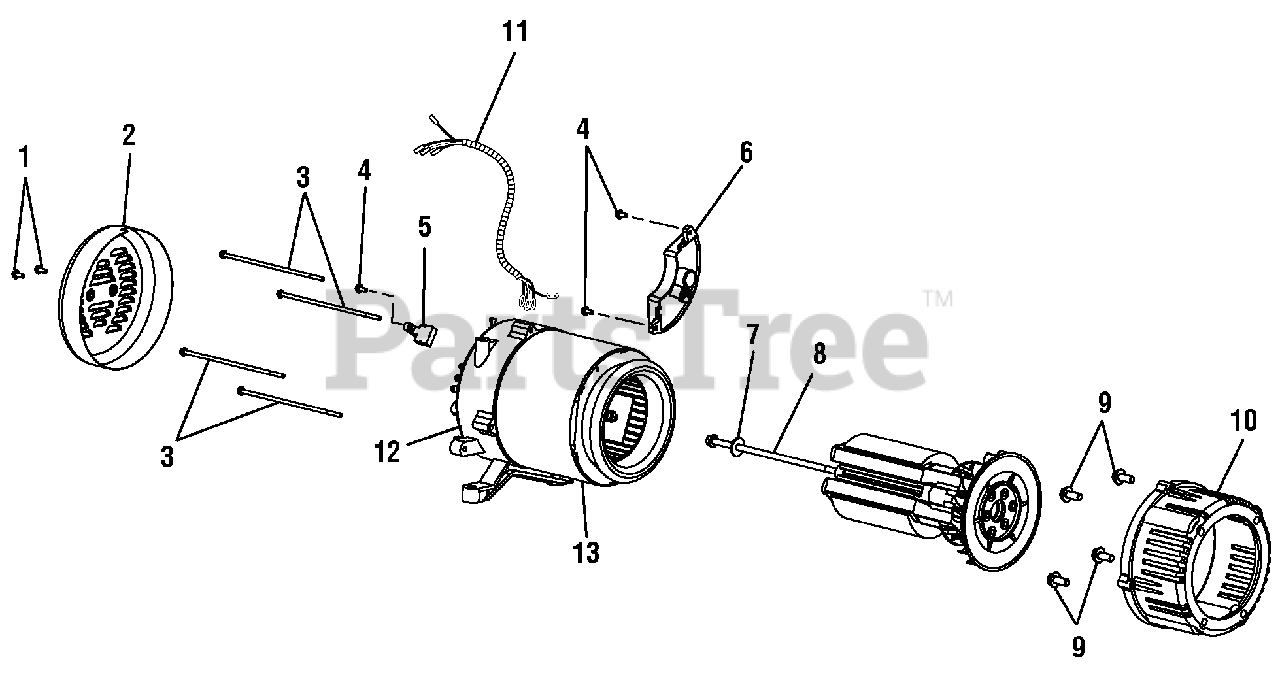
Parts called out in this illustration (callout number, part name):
2	Brush Cover
3	Bolt (M6 x 164 mm)
5	Brush Assembly
6	Automatic Voltage Regulator
7	Washer (5/16 in.)
8	Bolt (5/16-24 x 215 mm, Hex Hd.)
9	Bolt (3/8-18 x 1-1/4 in.)
10	Engine Adapter
11	Wiring Harness
12	Bearing Support
13	Generator Head Cover
